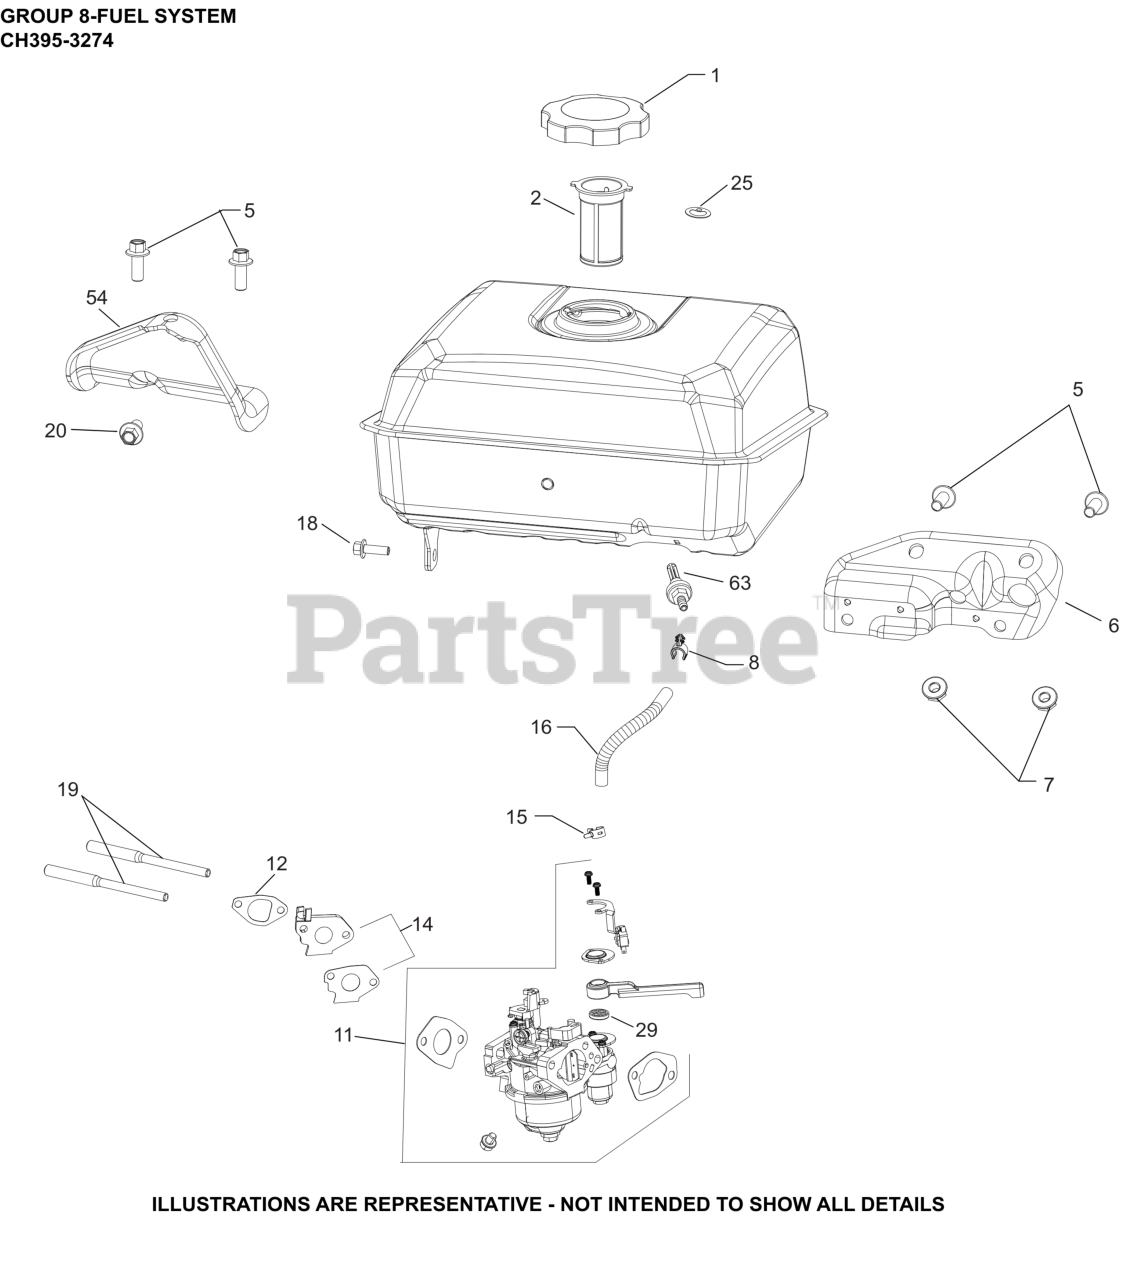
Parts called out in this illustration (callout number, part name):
1	CAP, FUEL TANK
2	FILTER, FUEL TANK
5	SCREW, M8 X 20
6	BRACKET, FUEL SUPPORT ASSEMBLY
7	NUT, FLG M8X1.25
8	CLIP, FUEL HOSE
11	KIT, CARBURETOR COMPLETE
12	KIT, INTAKE GASKETS
14	INSULATOR AND GASKET KIT
15	CLAMP, FUEL LINE
16	LINE, FUEL (10"-CUT TO LENGTH)
18	SCREW, M6 X18
19	STUD, CARBURETOR
20	SCREW, FLG 8X1.25X16
25	KIT, FUEL SCREEN
29	SEAL, INLET VALVE
54	BRACKET, FUEL SUPPORT
63	FITTING, FUEL ASSY
64	KIT, FUEL TANK
NI	KIT, HIGH ALT (4000-8000 FT)
NI	KIT, HIGH ALTITUDE (ABOVE 8,000 FT.)
NI	KIT, CARBURETOR REPAIR
